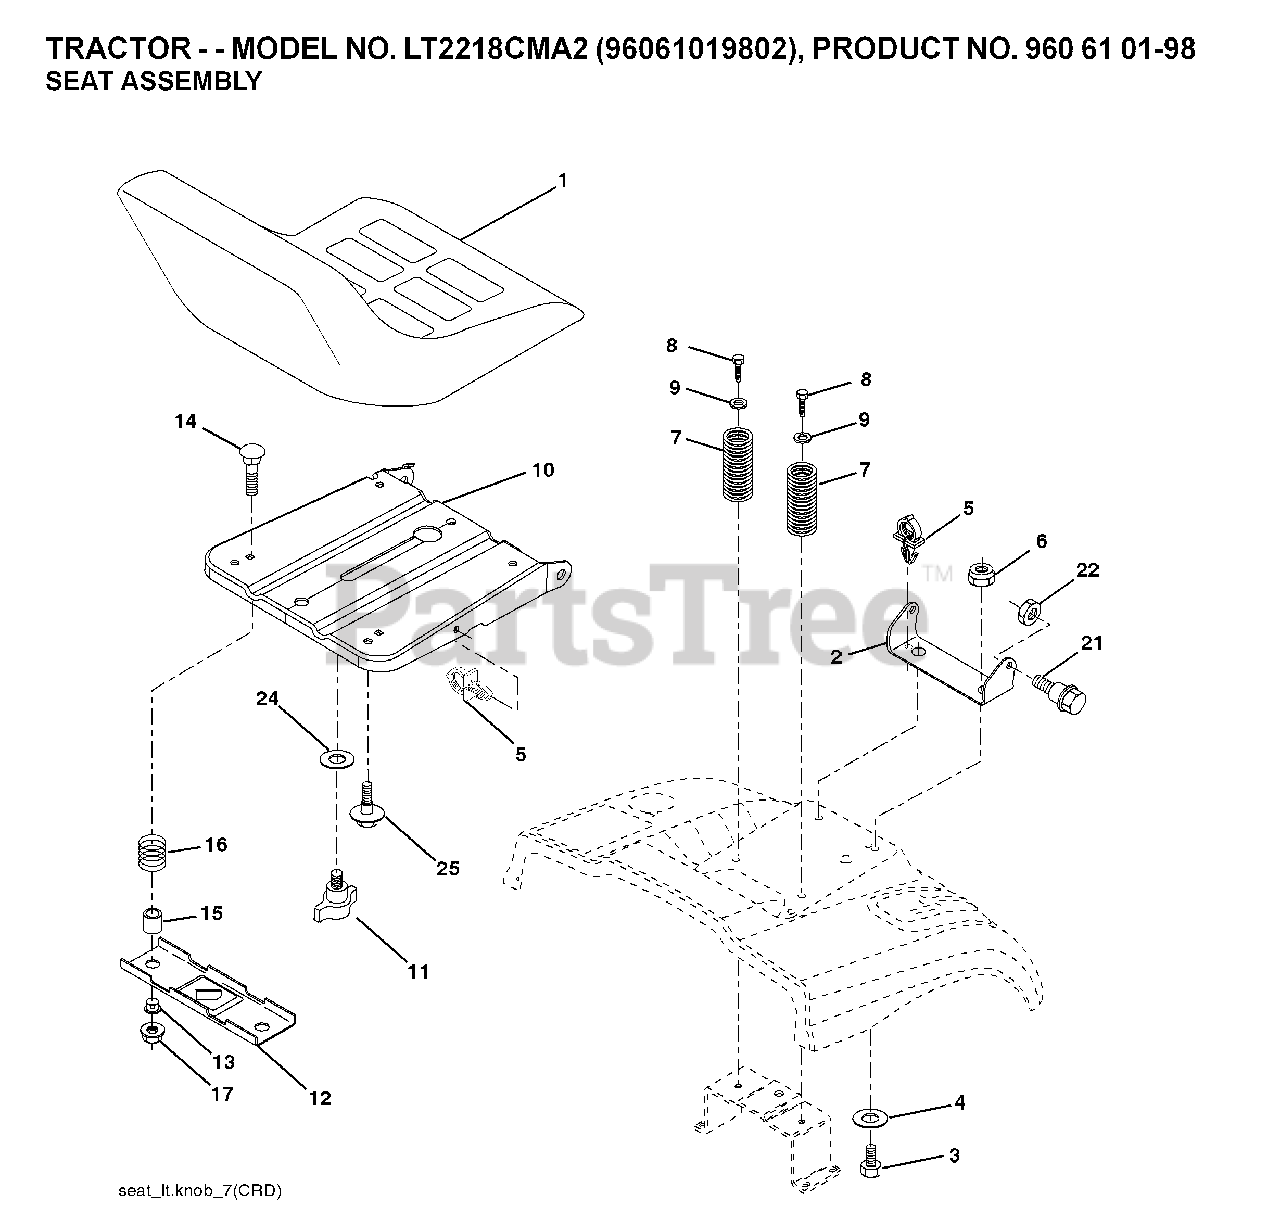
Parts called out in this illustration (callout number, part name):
1	SEAT.XG150.BLK.KB/SLD.NO-LOGO
2	SEAT PIVOT BRKT
4	WASHER PM
5	PUSH CLIP
6	NUT
7	SPRING COMPRESSION
8	SCREW 3/8-16X1
9	WASHER
10	PAN.ASM.SEAT.1SLOT
11	KNOB.SEAT.ADJ.WINGNUT
12	BRKT.MNTNG.SWITCH.SEAT
14	BOLT.ROUND.HEAD.SQUARE.NECK
15	SPACER SPLIT
16	SPRING COMPRESSED
17	NUT T
21	BOLT.SHOULDER.5/16-18
22	NUT.71038.31-18.HEX.NYLOCK
25	BOLT,SHOULD
